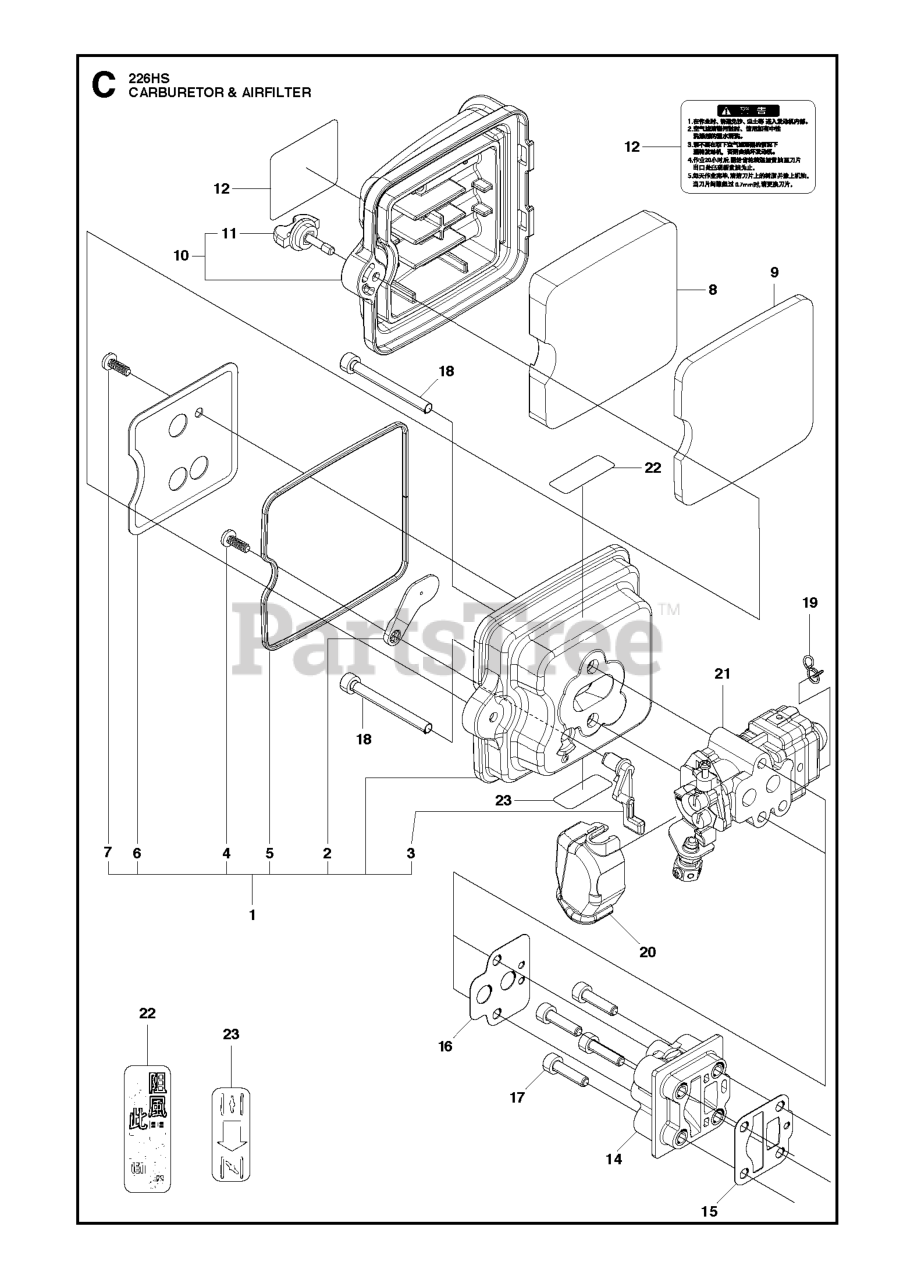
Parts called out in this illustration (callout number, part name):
1	FILTER HOUSING
2	PLATE.CHOKE
3	LEVER CHOKE
8	FILTER FOAM
10	COVER ASSY
12	LABEL.CAUTION
15	INSULATOR GASKET(R-848F0814B0)
16	GASKET, CARB (RPLS T155113131)
21	CARBURETTOR ASSY
22	LABEL.CHOKE
